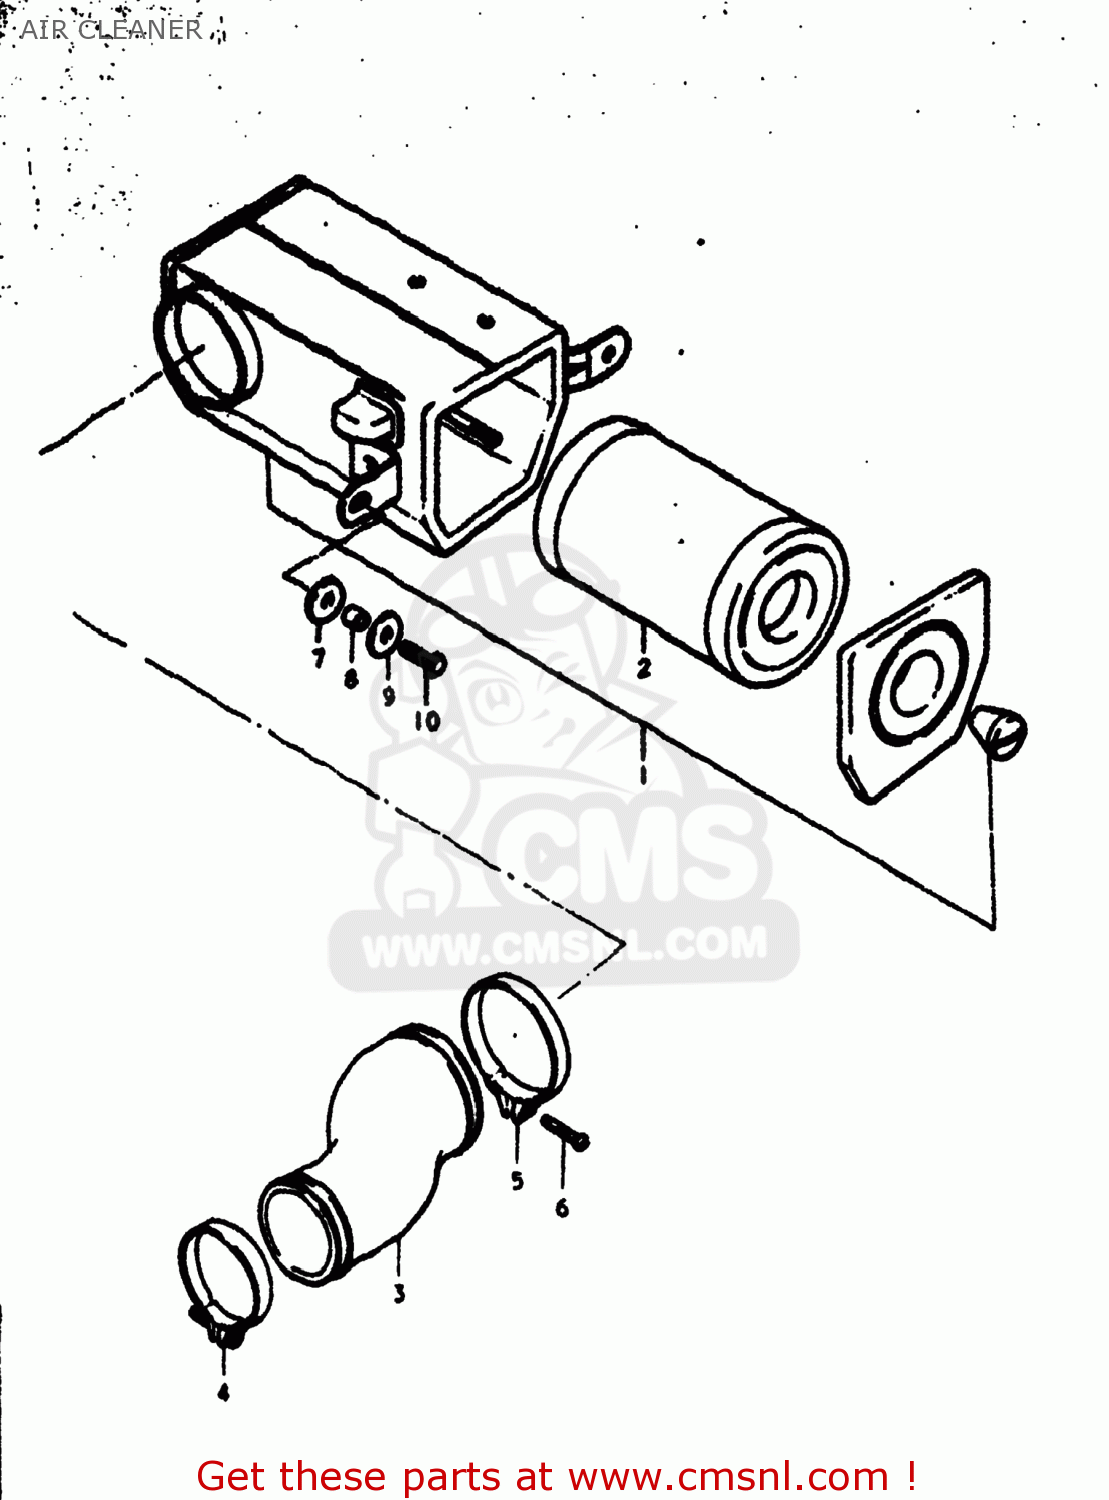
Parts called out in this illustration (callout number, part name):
1	CLEANER ASSEMBLY,AIR
2	FILTER ASSY,AIR CLEANER
3	TUBE,AIR CLEANER OUTLET
4	CLAMP
5	CLAMP
6	SCREW TAPP.
7	CUSHION
8	SPACER (6.1X8X9.5)
9	WASHER
10	BOLT
